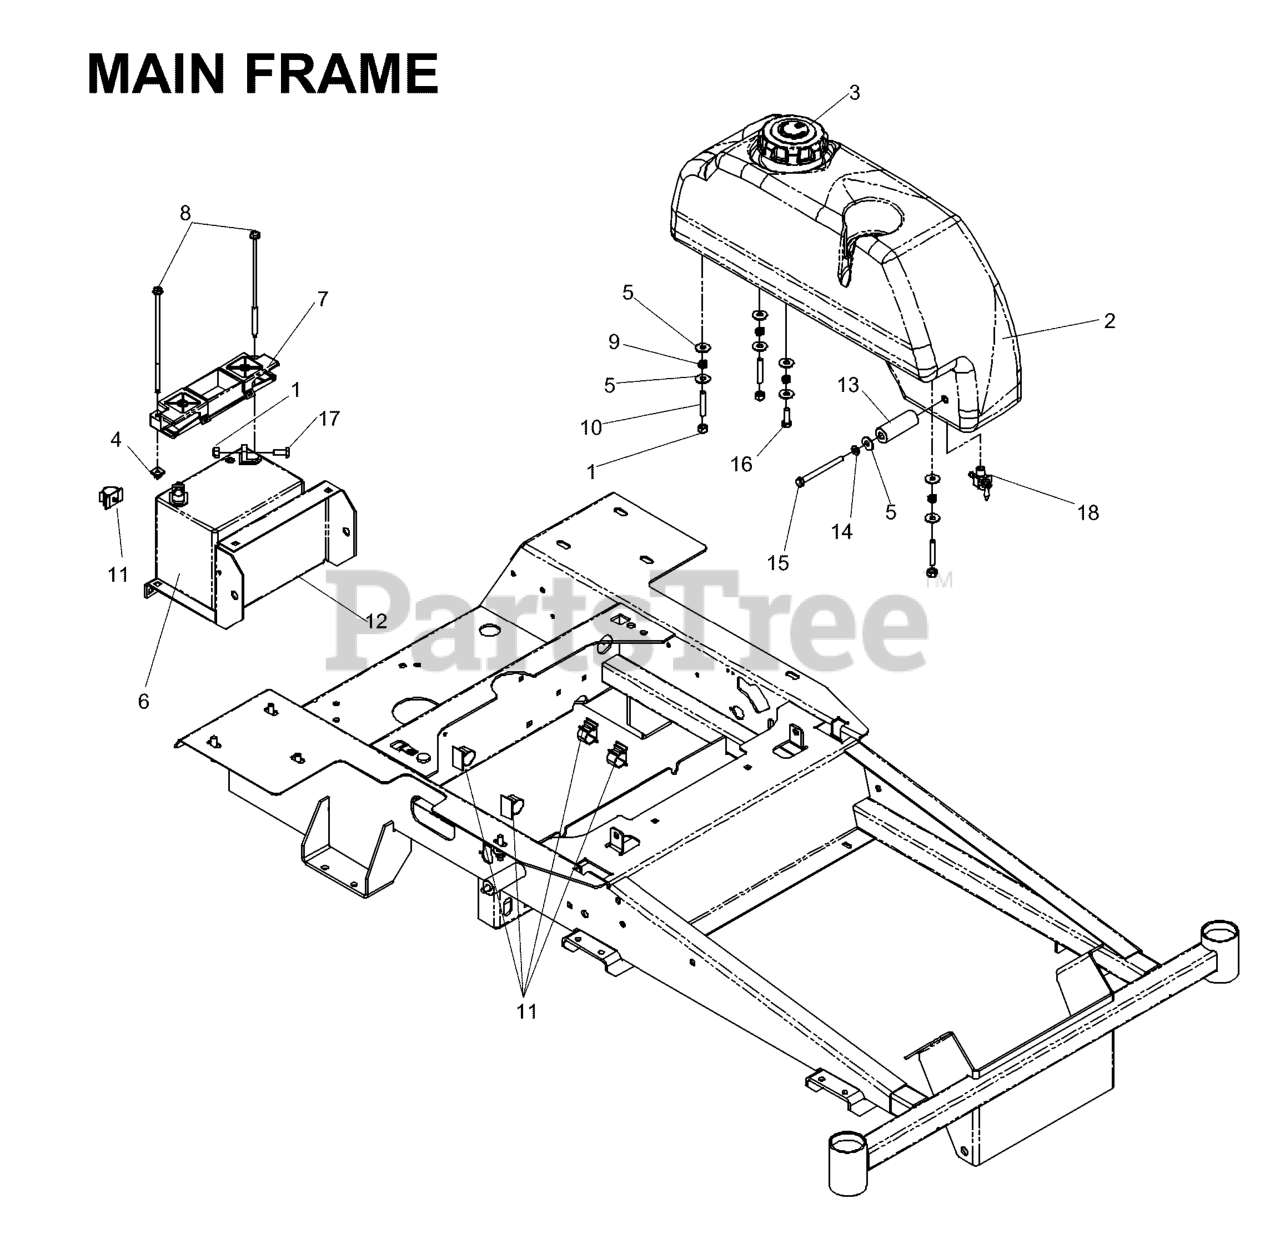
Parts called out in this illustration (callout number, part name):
1	NUT 5/16 NYLOC
2	LEFT TANK W/CUP HOLDER
3	FUEL CAP ANTI-SPLASH
4	PUSH NUT-NYLON
5	WASHER 5/16 FLAT
6	BATTERY, 12 V 330 AMP
7	BATTERY HOLD DOWN
8	BOLT - 1/4-20 X 7.5
10	STUD, 5/16C
11	PUSH-MOUNT WIRE CLIP
12	BATTERY TRAY
13	TANK SPACER
14	WASHER.LOCK.HVY.HLCL.SPR.5/16
15	BOLT - HCS 5/16C X 3.5
16	HCS 5/16C X 1
17	HCS 5/16C X 3/4
18	FUEL VALVE
